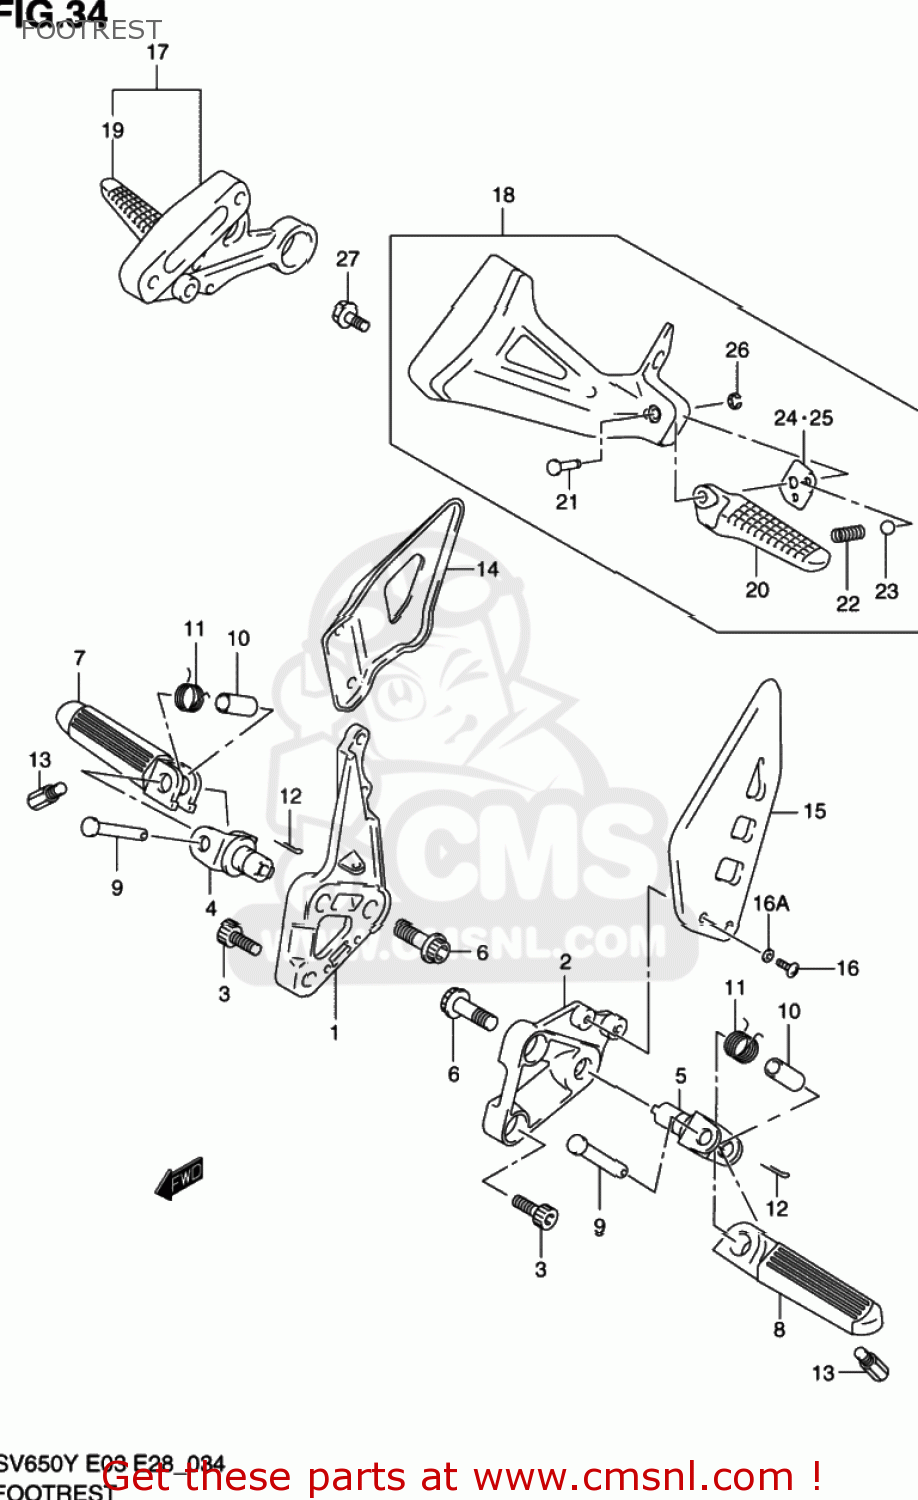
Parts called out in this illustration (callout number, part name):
1	BRACKET,FR FOOTREST,R
2	BRACKET,FR FOOTREST,L
3	BOLT
4	HOLDER,FOOTREST,R
5	HOLDER,FOOTREST,L
6	BOLT(10X28)
7	BAR,FR FOOTREST,R
8	BAR,FR FOOTREST,L
9	PIN
10	SPACER(8.1X12X22)
11	SPRING
12	PIN 20X15
13	BOLT,BANK SENSOR
14	GUARD,FR FOOTREST,R
15	GUARD,FR FOOTREST,L
16	SCREW(5X16)
16A	WASHER(8.1X14X1.2)
17	FOOTREST ASSY,PILLION,R
18	FOOTREST ASSY,PILLION,L
19	BAR,PILLION FOOTREST,R
20	BAR,PILLION FOOTREST,L
21	PIN
22	SPRING
23	BALL
24	PLATE,PILLION FOOT,R
25	PLATE,PILLION FOOT,L
26	E-RING
27	BOLT
